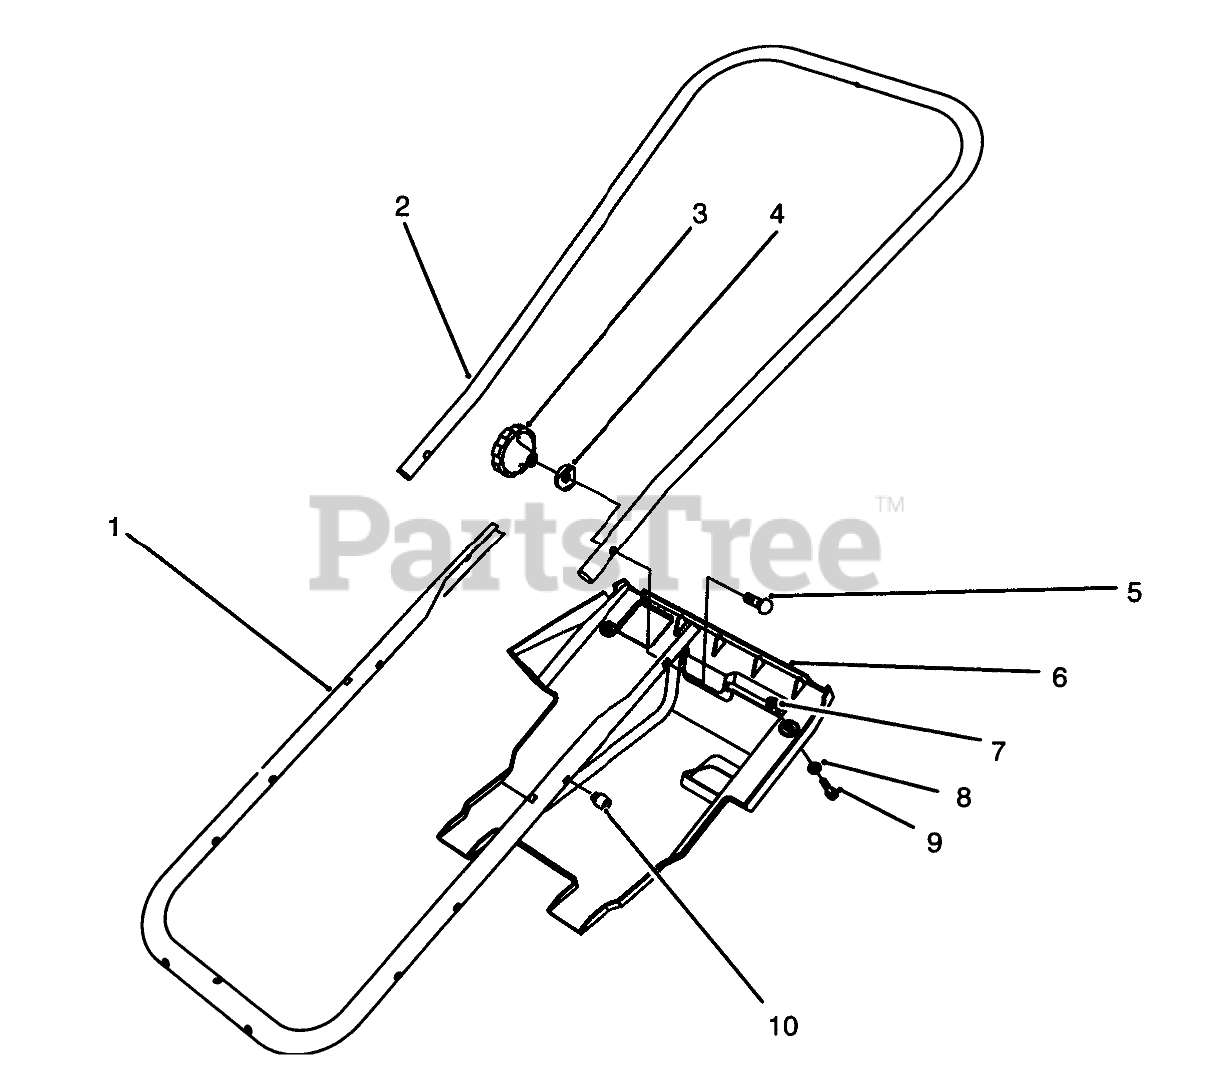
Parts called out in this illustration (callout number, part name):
1	Tube-Frame
2	Handle-Upper
4	WASHER-CURVED
5	SCREW-HANDLE
6	SHROUD
7	Nut-Push
8	WASHER-FLAT
9	SCREW-HWHTF
10	NUT-EXPANSION
